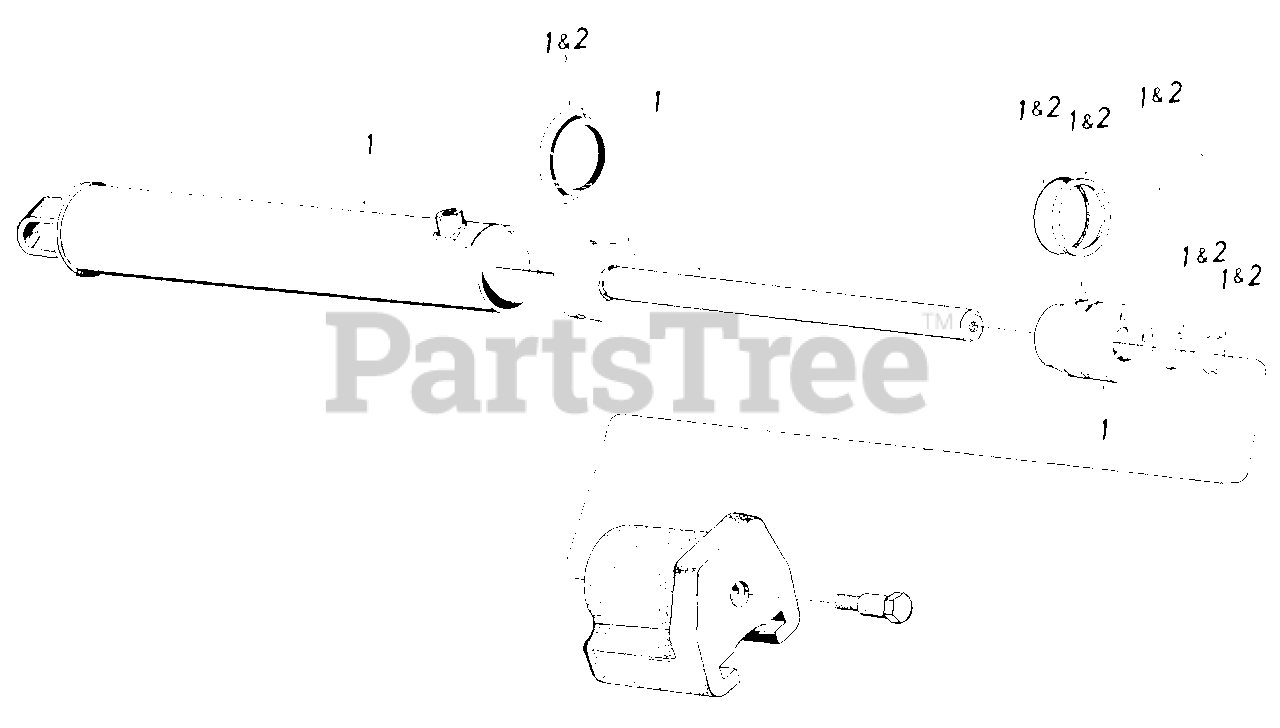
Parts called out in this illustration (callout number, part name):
1	Cylinder Ass'y. Comp
2	3-1/2" Cyl. Kit "O"-Ring Set
2	4" Cyl. Kit "O"-Ring Set
